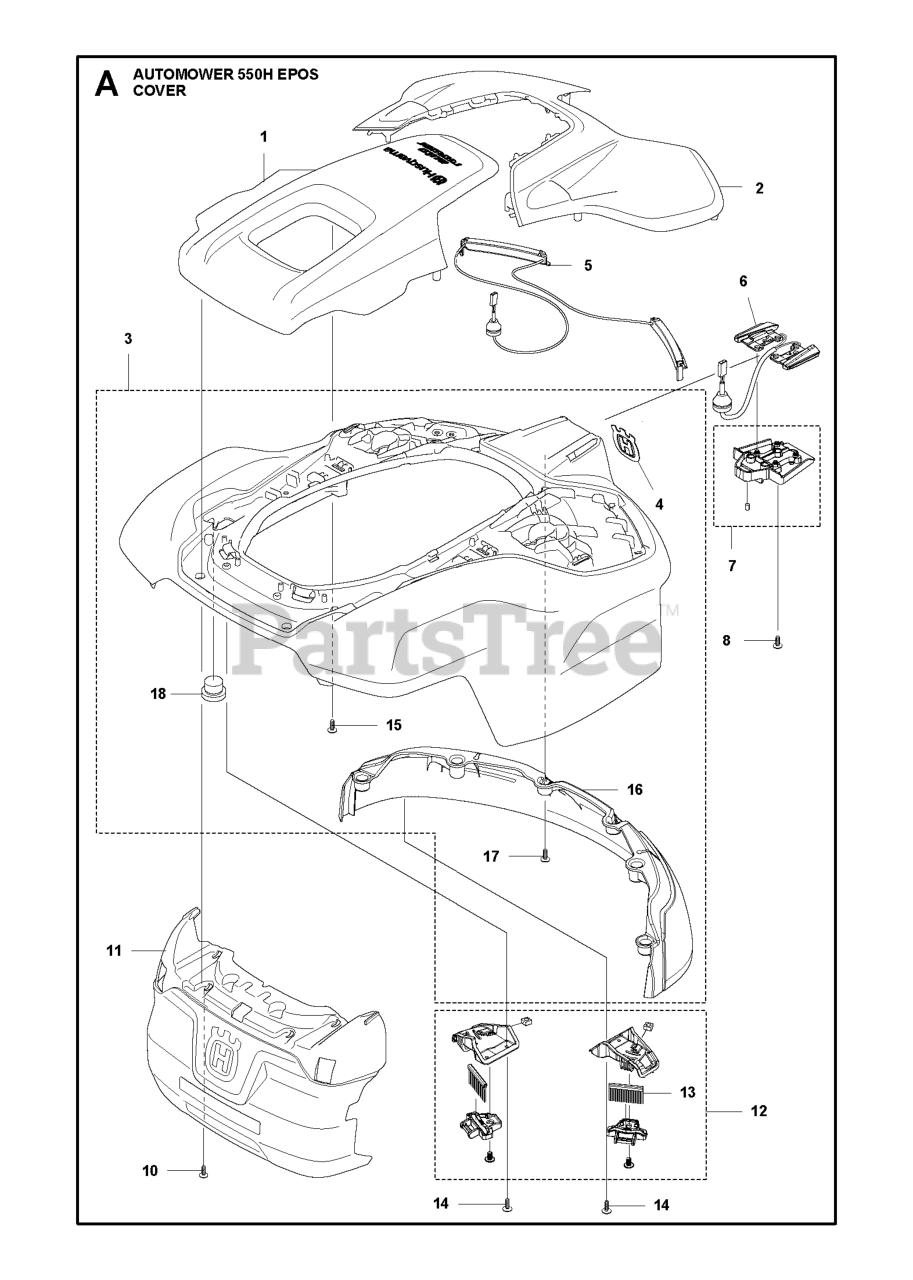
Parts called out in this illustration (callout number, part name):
1	REAR COVER TOP GREY
2	FRONT COVER TOP ORANGE
3	BODY ASSY 430XH, 450XH
4	DECAL HUSQVARNA CROWN HEIGHT 5
5	WIRING ASSY LED LIGHT WIRING O
6	CABLE ASSY CHARGING PLATE
7	HOLDER ASSY 430XH, 450XH
8	SCREW 14MM
10	SCREW ITXPANT
11	BUMPER ASSY 430XH,450XH,550H
12	BRUSH KIT 430/450
13	WHEEL BRUSH REFILL KIT
14	SCREW 14MM
15	SCREW ITXPANT
16	BUMPER FRONT
17	SCREW ITXPANT
18	CAP SNAPLOC
